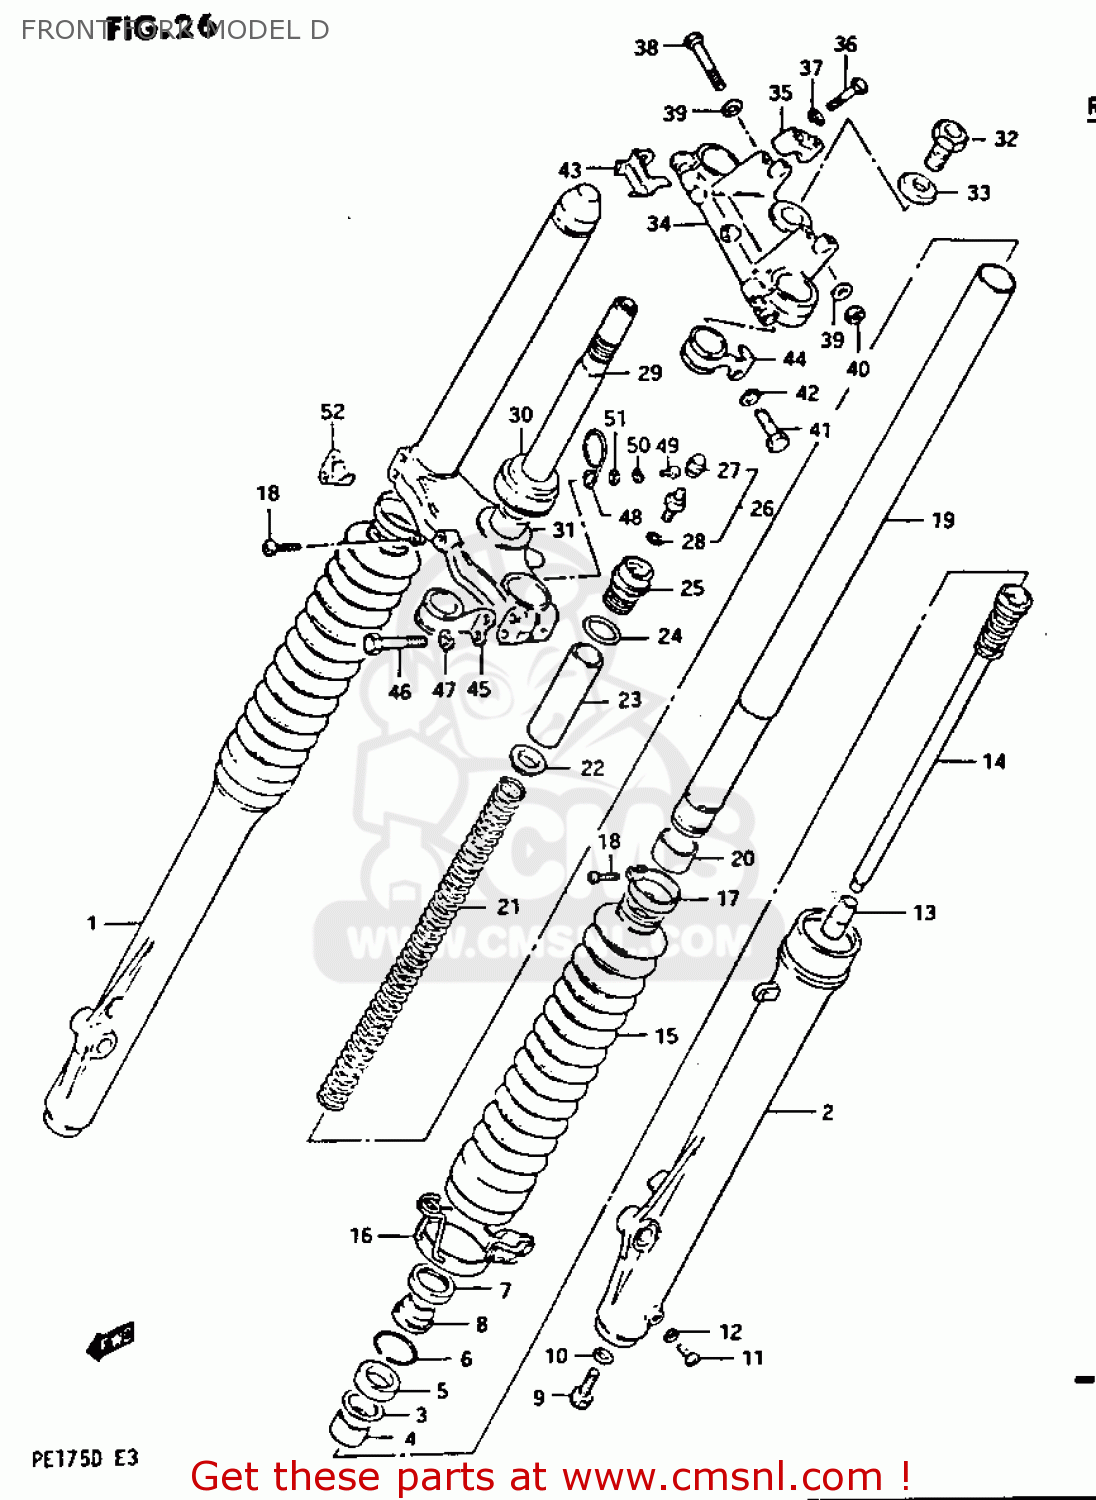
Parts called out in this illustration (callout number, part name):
1	DAMPER SET
2	TUBE,OUTER,LEFT
3	WASHER(40X50X2.3)
4	METAL,SLIDE
5	SEAL,OIL
6	RING,STOPPER
7	CASE,DUST SEAL
8	SEAL,DUST
9	BOLT,CYLINDER
10	GASKET,CYLINDER (NAS)
11	SCREW
12	GASKET,DRAIN,PLUG (NAS)
13	PIECE,OIL LOCK
14	CYLINDER,FRONT FORK
15	BOOT
16	BAND,FORK COVER BOOT
17	BAND,BOOT
18	SCREW
19	TUBE,FORK,INNER
20	PISTON
21	SPRING,FRONT FORK
22	GUIDE
23	SPACER,FRONT FORK SPRING
24	O RING
25	CAP,FORK INNER TUBE
26	VALVE,FRONT FORK AIR
27	CAP,VALVE
28	O-RING
29	STEM,STEERING
30	BEARING(30X55X17)
31	WASHER,THRUST
32	BOLT
33	WASHER
34	HEAD,STEERING STEM
35	HOLDER,HANDLEBAR
36	BOLT
37	LOCK WASHER
38	BOLT 8X50
39	WASHER
40	NUT
41	BOLT
42	WASHER,LOCK,10
43	BRACKET,TOOL FITTING,UPPER
44	GUIDE,CABLE
45	CLIP,CABLE
46	BOLT 8X45
47	LOCK WASHER
48	CLIP
49	SCREW
50	WASHER,LOCK
51	WASHER
52	BRACKET,TOOL FITTING,LOWER
